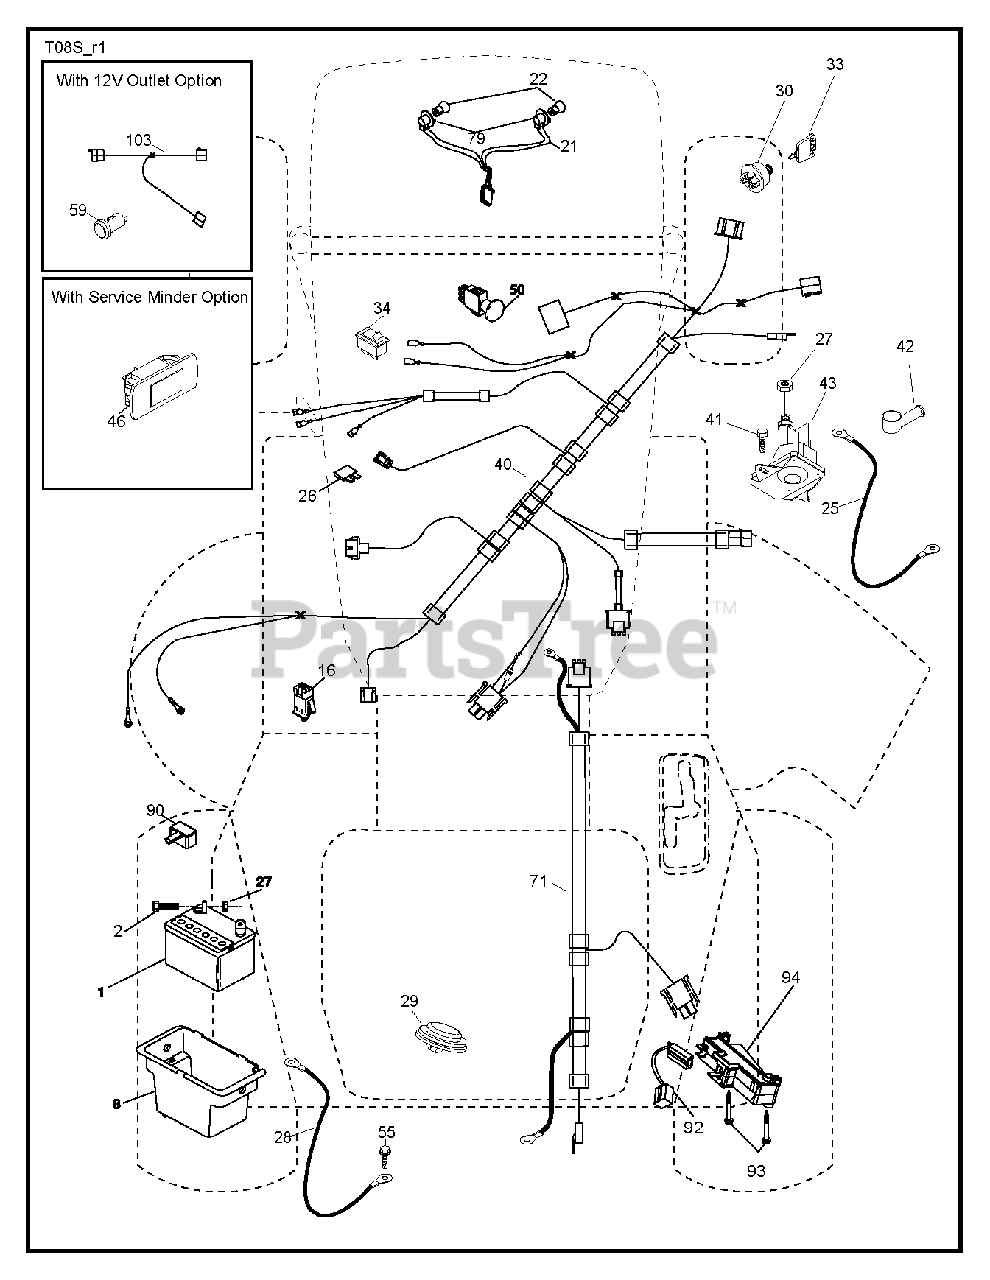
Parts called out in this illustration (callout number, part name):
1	REPL BY 532 12 38-99
8	BOX.BATTERY.MNT.REAR.L
16	SWITCH INTERLOOK PUSH-IN
21	HARNESS.LIGHT W/4152J BULBS
22	LIGHTBULB
25	CABLE.STARTER.6G.BL/RED.17.5
26	FUSE 20AMP
27	NUT
28	CABLE.BLACK.18"REAR.BA
29	SWITCH.SEAT.DELTA.OPC.
30	SWITCH.IGN.DELTA.W.LGH.ROS
33	KEY.CHAIN.BLISTER.PACK.GEN.INT
34	SWITCH LT
40	HARNESS.IGN.DASH.HUQ/P
41	SCREW
42	TERMINAL COVER
43	SOLENOID.W/BRASS.PLUNG
46	GUAGE.SRVCMNDR.HRMTR.
50	PTO SWITCH
55	SCREW 5/16"
79	BULB HOLDER ASM.
90	COVER.TERMINAL.BATTERY
92	HARNESS.PIGTAIL.CONSLE
93	SCREW.PLASTITE
94	MODULE.REVERSE.ROS
